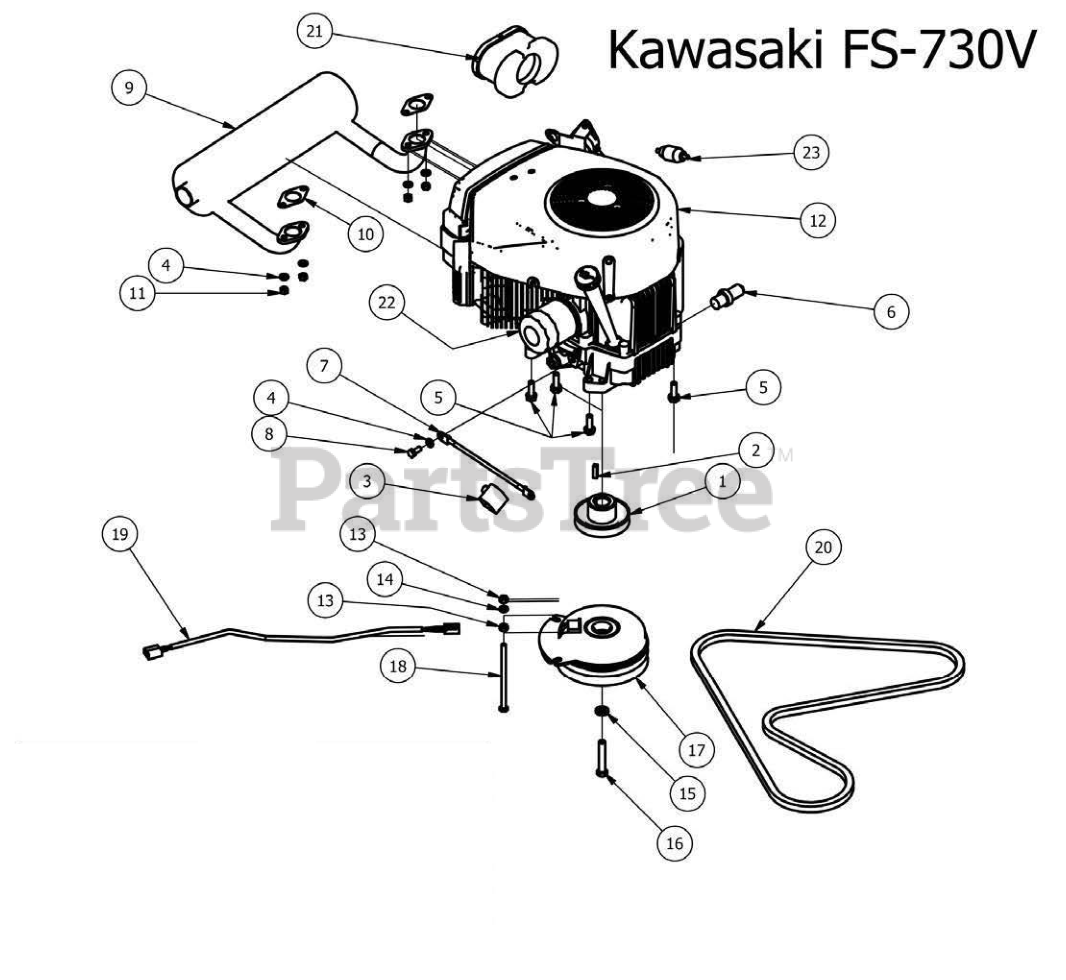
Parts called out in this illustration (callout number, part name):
1	3-3/4" Motor Pulley
2	1/4" x 1" Key
3	Black Boot For ground cable
4	5/16" Lock Washer
5	3/8 x 1 1/8 bolt
7	Starter to chassis cable
8	M8x1.20x20MM Hex head bolt
9	Kawasaki Exhaust
10	Exhaust gasket
11	M8-1.25 Zinc Nut
12	FS730V Engine
14	5/16" Lock Washer
15	7/16" Lock Washer
16	7/16" x 2 1/2" Hex Bolt
17	Clutch Assembly
18	5/16-18 x 5-1/2 GR 5 Hex Bolt
19	Clutch Pigtail
21	Kaw air Filter For Engine
22	Oil Filter
23	Universal inline Fuel Filter
